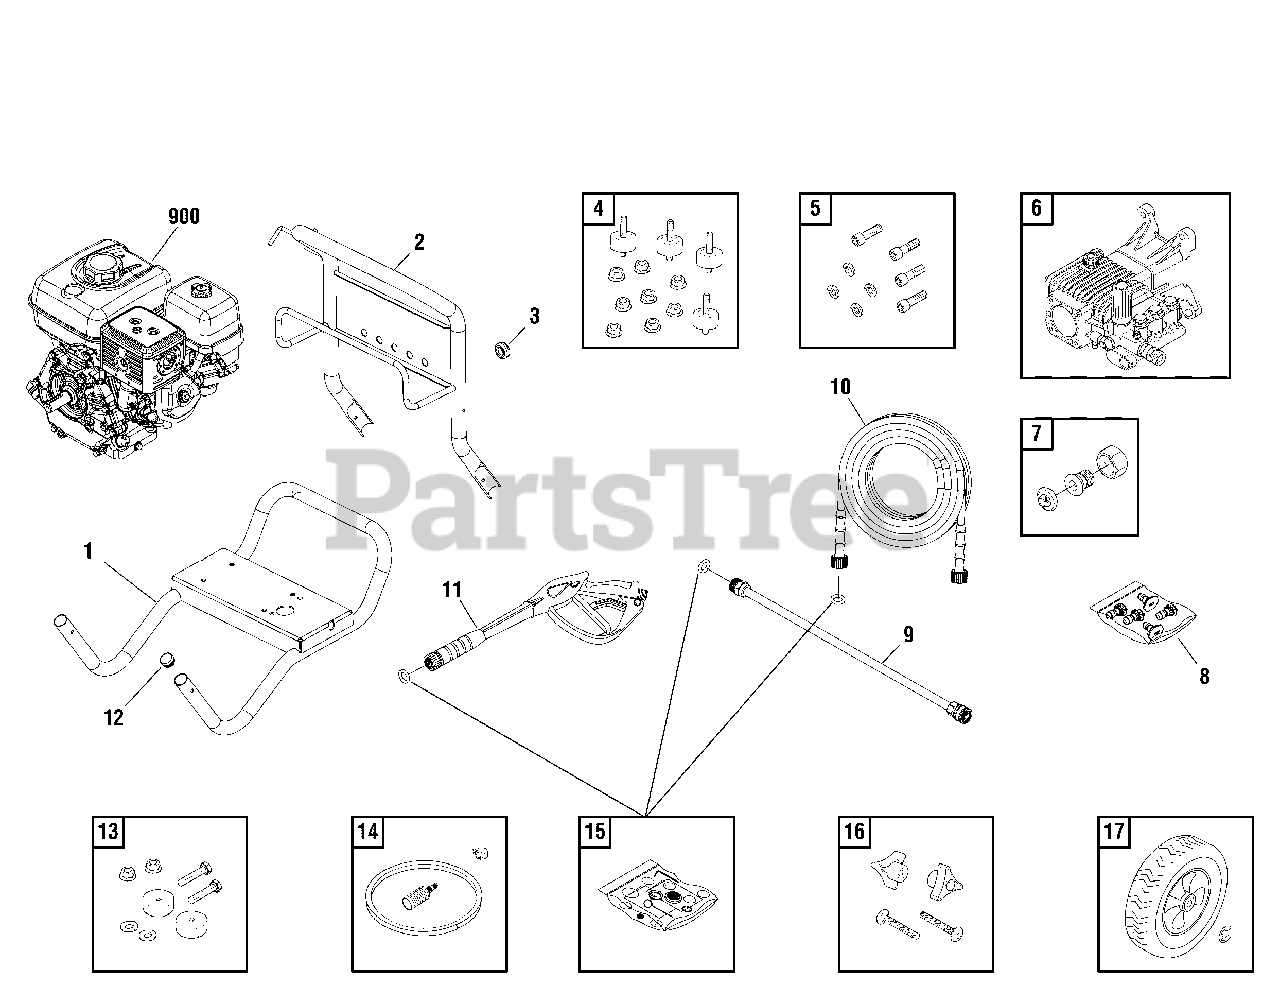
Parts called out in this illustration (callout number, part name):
4	KIT-HRDWR ENGINE MOUNTING
5	KIT-HRDWR PUMP MOUNTING
7	ADAPTER-GARDEN HOSE
9	EXTENSION-QC
11	GUN
13	MOUNT-VIBRATION
16	KIT-HARDWARE HANDLE
900	** ENGINE
